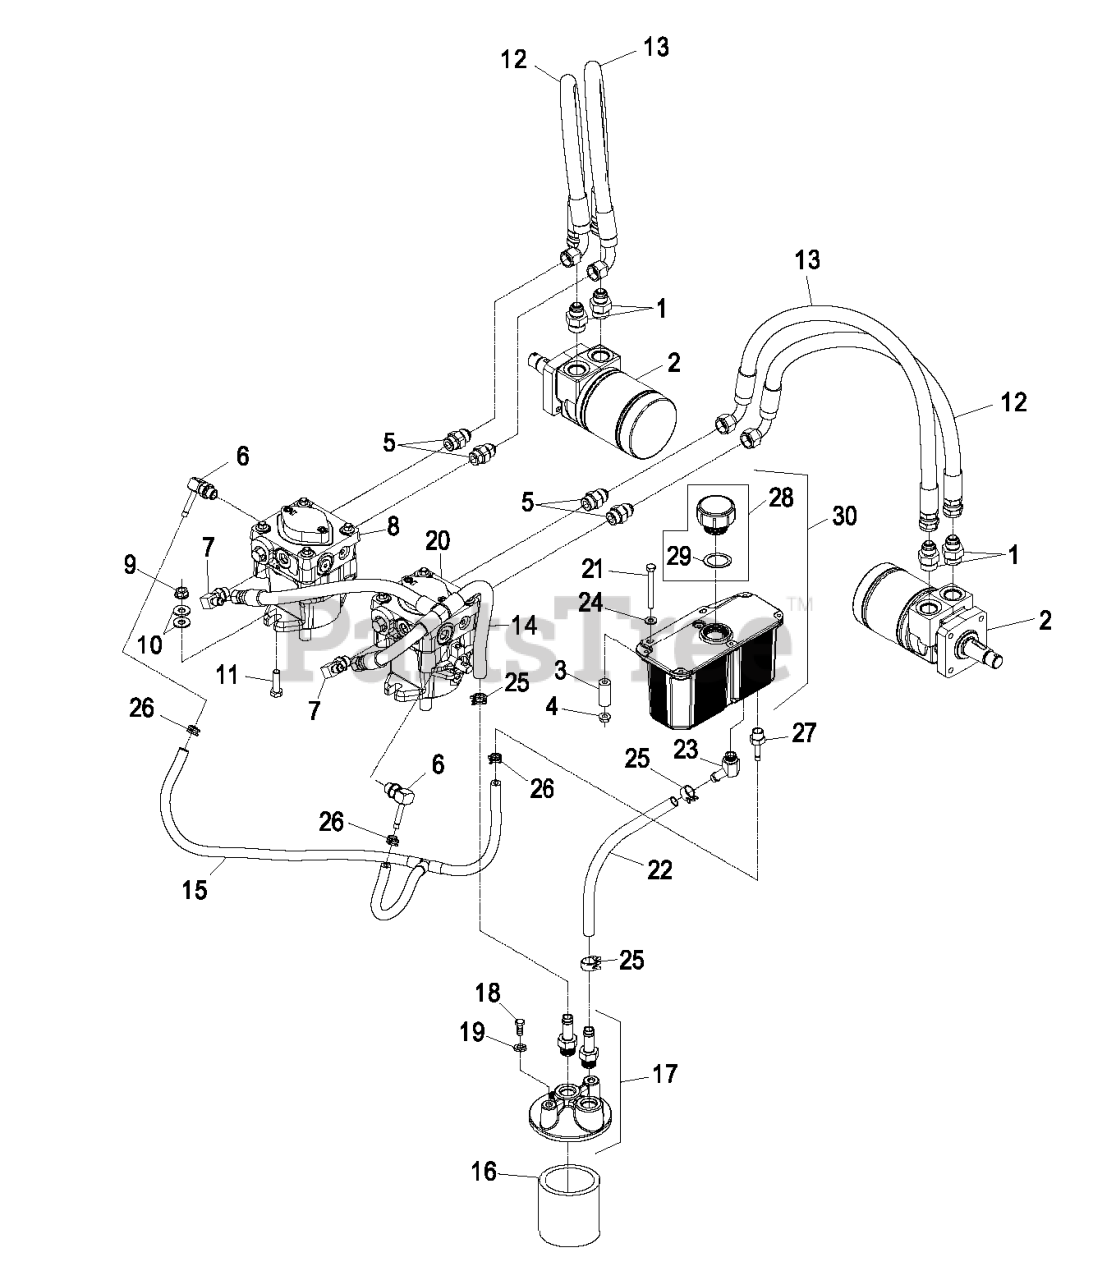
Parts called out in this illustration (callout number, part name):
1	FITTING-STRAIGHT
2	HYD MOTOR ASM
5	FITTING-STRAIGHT
6	ELBOW-90 DEG
7	FITTING-ELBOW, 90 DEG
9	NUT-HHF, WHIZ
10	WASHER-FLAT
11	SCREW-HH
13	HOSE-PRESSURE, HIGH
14	CHARGE HOSE ASM
15	CASE DRAIN HOSE ASM
16	FILTER-25 MICRON, BI-DIRE
17	FILTER HEAD ASM
18	SCREW-HH
19	WASHER-LOCK
21	SCREW-HH
22	HOSE-CHARGE
23	FITTING-BARBED, 45 DEG
24	WASHER-FLAT
25	CLAMP-HOSE
26	CLAMP-HOSE
27	ADAPTER-STRAIGHT
28	KIT,HYD RES CAP W/GASKET
29	GASKET-CAP
30	HYD RESERVOIR ASM
